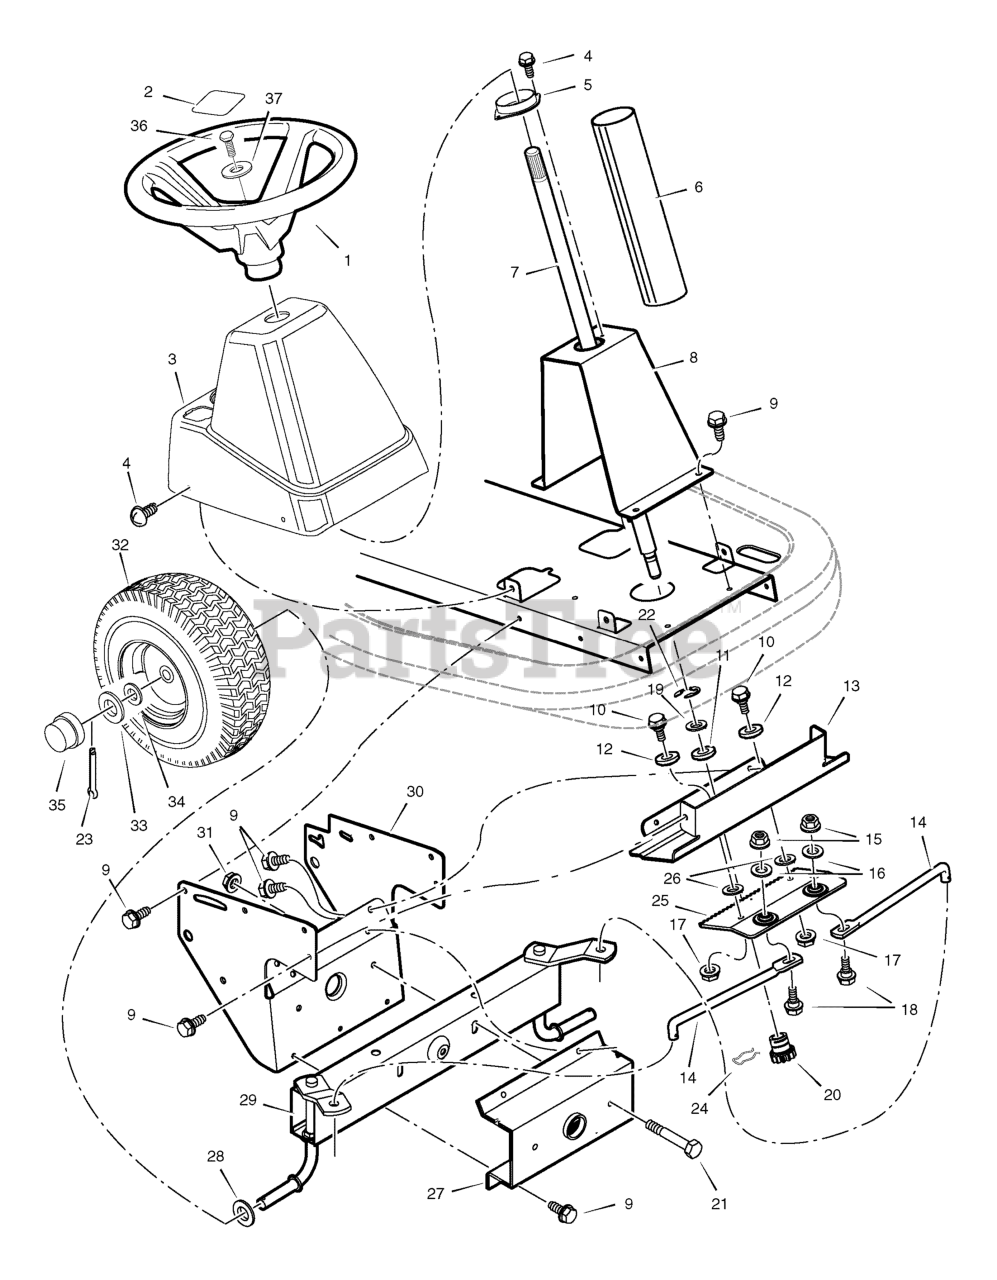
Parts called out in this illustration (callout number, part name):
1	WHEEL, Steering
2	INSERT, Steering
3	CONSOLE, Low (Black)
4	SCREW
5	BEARING, Upper Steering
6	TUBE, Steering
7	SHAFT, Steering
8	SUPPORT, Steering
10	BOLT, Shoulder
11	BEARING, Lower Steering
13	PLATE, Gear Mounting
15	NUT, Flange
16	WASHER
17	NUT, Flange
18	BOLT, Hex
20	GEAR, Pinion
21	BOLT, Hex
22	E-RING, Retainer
23	PIN, Cotter
24	RETAINER, Spring
25	RACK, Steering
27	BRACKET, Axle Front
29	AXLE & SPINDLE ASSEMBLY
30	BRACKET, Support
31	NUT, Flange
32	WHEEL, Front
35	CAP, Hub
36	Screw, Hex
37	WASHER
